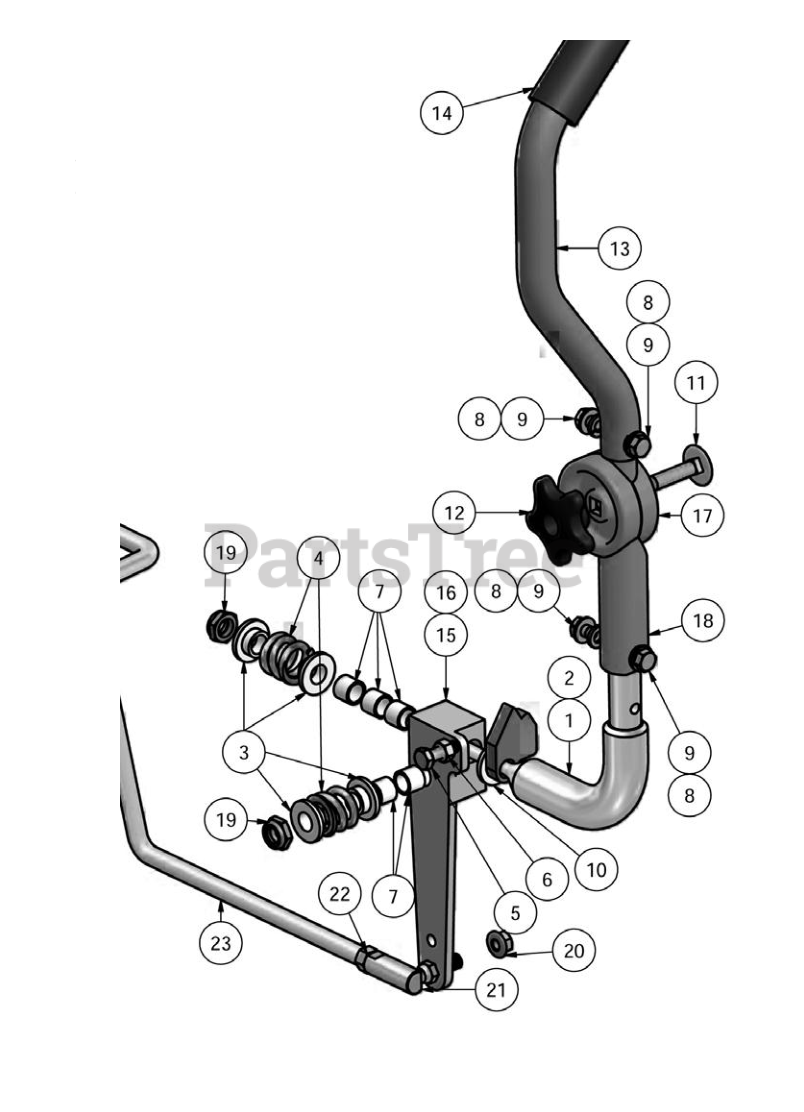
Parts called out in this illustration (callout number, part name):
1	Steering Arm Base-Right
2	Steering Arm Base-Left
3	.515 ID Nylon Shoulder Washer
4	Drive Lever Spring
5	5/16" x 3/4" Hex Bolt
7	.507 ID Nylon Bushing
8	5/16" Lock Washer
9	5/16" x 1/2" Flange Bolt
10	.635 ID Plastic Washer
11	3/8" x 1-1/4" Carriage Bolt
12	Black Knob for Adjustable Steering Arm
13	Upper Steering Arm Tubing-Adjustable
14	Black Steering Grips
15	Drive Arm Lever Housing (Left)
16	Drive Arm Lever Housing (Right)
17	Lower Adjuster for Steering Arm
18	Upper Adjuster for Steering Arm
19	1/2" Nylcock Nut (1/2 Jam)
20	5/16" Flange Nut
21	3/8-24 Ball Joint
22	3/8" Fine Threaded Jam Nut
23	Transaxle Drive Rod (Right)
24	3/8-24 Ball joint (female/male)
